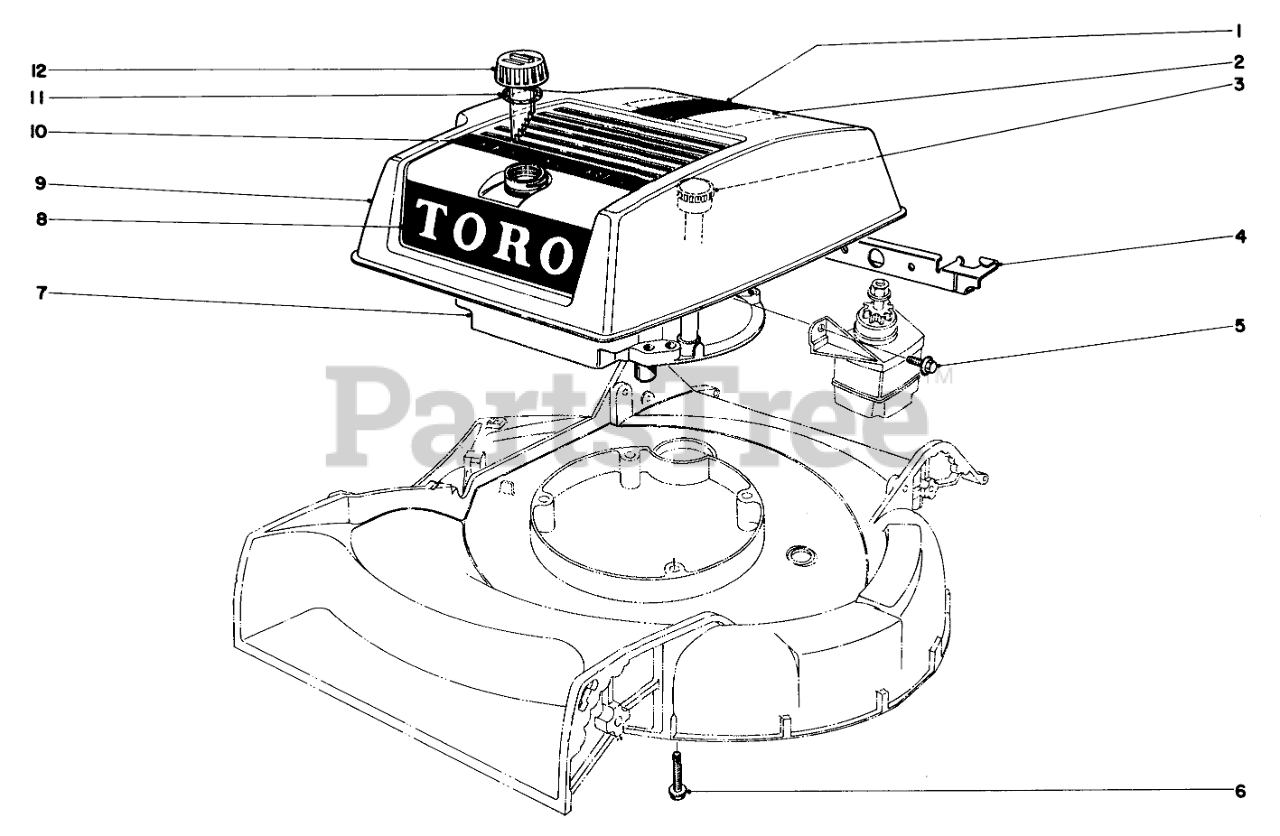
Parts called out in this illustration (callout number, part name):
1	Decal
2	Decal-Maintenance
3	Dip Stick
4	Shroud Bracket
5	SCREW
6	3/8-16 X 2-3/4 CAPSCR
7	Engine
8	Decal-Toro
9	Shroud
10	Decal-Key-Lectric
11	Gasket
12	Gas Cap (Incl. Ref. No. 11)
